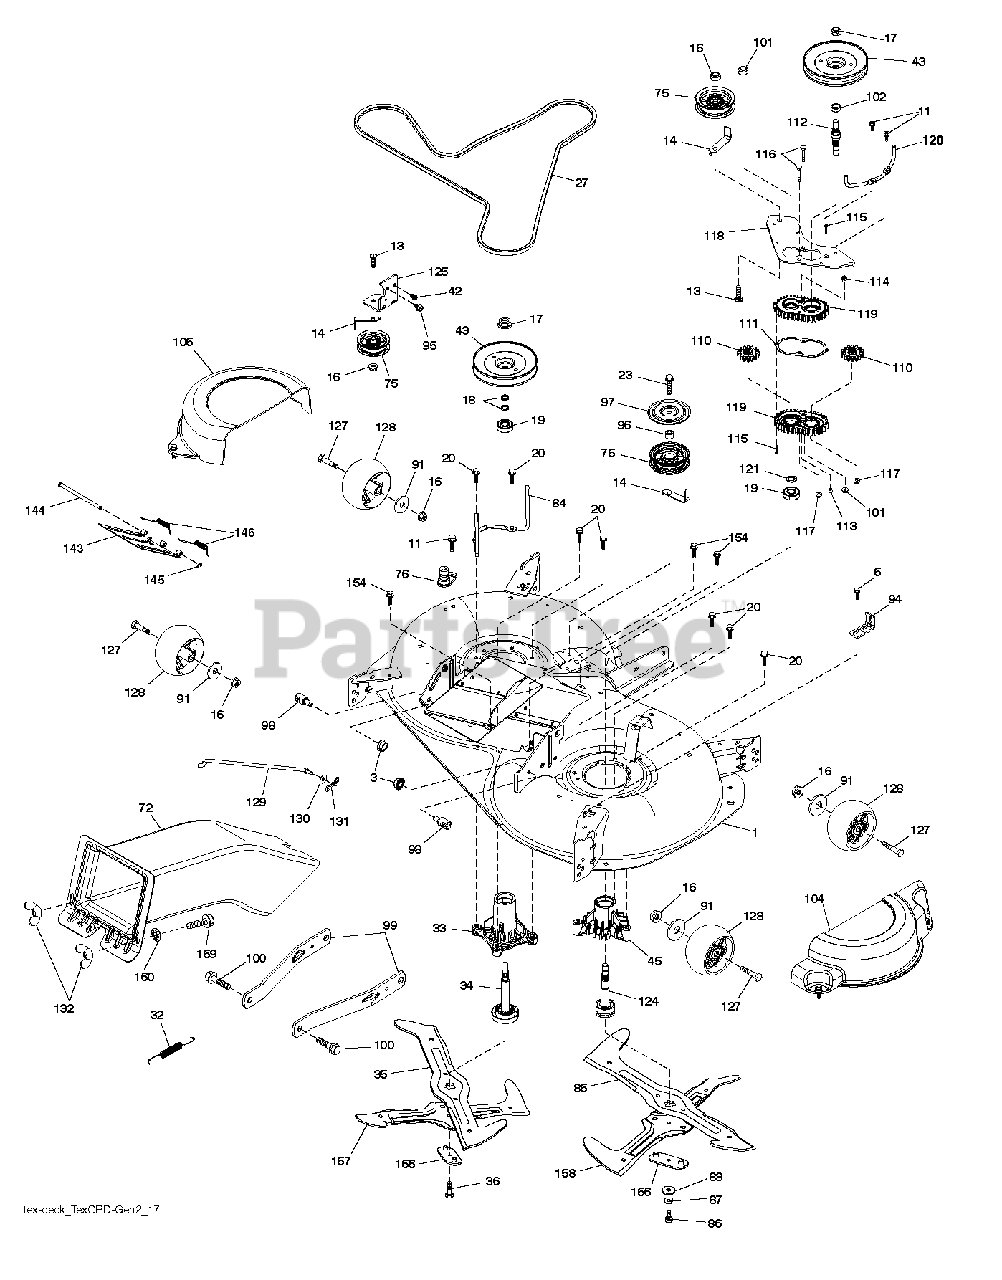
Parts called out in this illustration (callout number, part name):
3	NUT LOCK HEX FLANGE 5/16-18
5	BOLT.5/16HEX.WHS.HD
11	SCREW.1/4-20X5/8
13	BOLT.3/8-16X1.50
14	KEEPER, BELT IDLER
16	NUT LOCK FLG 3/8-16 UNC
17	NUT.FLANGE.LOCK.TOP
18	WASHER.SPACER.MANDREL
20	SCREW, WASHER HEAD
23	SCREW LT
27	BELT BELT. ELECTRIC MOWER DRIV
32	SPRING 107CM & 97CM ELECTRIC D
33	HOUSING.MANDREL.4PT.
34	SHAFT.ASM.MDRL.N/GREASE.38
35	BLADE.3N1.LH.CRD
36	BOLT.WASHER.ASM.7/16-2
42	SCREW
43	PULLEY PULLEY MANDREL 5.438 PD
45	HOUSING.MANDREL.44/46" VENT
72	RP 97107.TEX.CRD.UPPE
75	FLAT IDLER PULLEY
76	PORT.WASHOUT
84	KEEPER KEEPER. LH MANDREL BELT
85	BLADE.3N1.RH.CRD
86	BOLT.3/8-24X1.25GR8. LHTHRD
87	LOCKWASHER
88	WASHER.BLADE
91	WASHER
94	BRKT.CLUTCH.CABLE
95	SCREW, 3/8-16X3/4
96	SPACER
97	PROTECTOR
98	STUD.FASTNER.W/ANTI-ROTATE
99	ARM.SUSPENSION.MOWER.R
100	BOLT.SHOULDER
101	NUT.CROWNLOCK.9/16 -18.UNC
102	SPACER BEARING
110	GEAR GEAR OUTPUT
111	GASKET GASKET GEARCASE
112	SHAFT SHAFT. CRD GEARCASE ADAP
113	PLUG PLUG OIL
114	VALVE VALVE RELIEF
115	SCREW
116	BOLT.CARIGE.SS.1/4-20X1.75GR5
117	NUT T
118	ARM ARM. CLUTCHING 107 TEX CRD
119	GEARCASE GEARCASE SUBASM
120	KEEPER KEEPER. RH MANDREL BELT
121	WASHER WASHER
124	MANDREL SHAFT NON/GREASE
125	BRACKET
127	BOLT.SHOULDER.3/8-16X3-5/8.
128	WHEEL. GUAGE RALLY
129	ROD ROD. SWAY CRD GEN II
130	WASHER
131	PIN.COTTER.5/16.BOW TI
132	KNOB.HANDLE.3/8.TRI-POINT.BLAC
143	COVER DOOR.107 CM CRD EZ MULCH
144	PIN PIN.HINGE
145	E-RING.5/16"
146	SPRING SPRING: EZ MULCH DOOR
154	SCREW T-30 1/4-20 X
156	ADAPTER ADAPTER.CROSSBLADE.107
157	BLADE 107CM.CROSS.BLADE
158	BLADE.CROSS.RH.CRD.107
